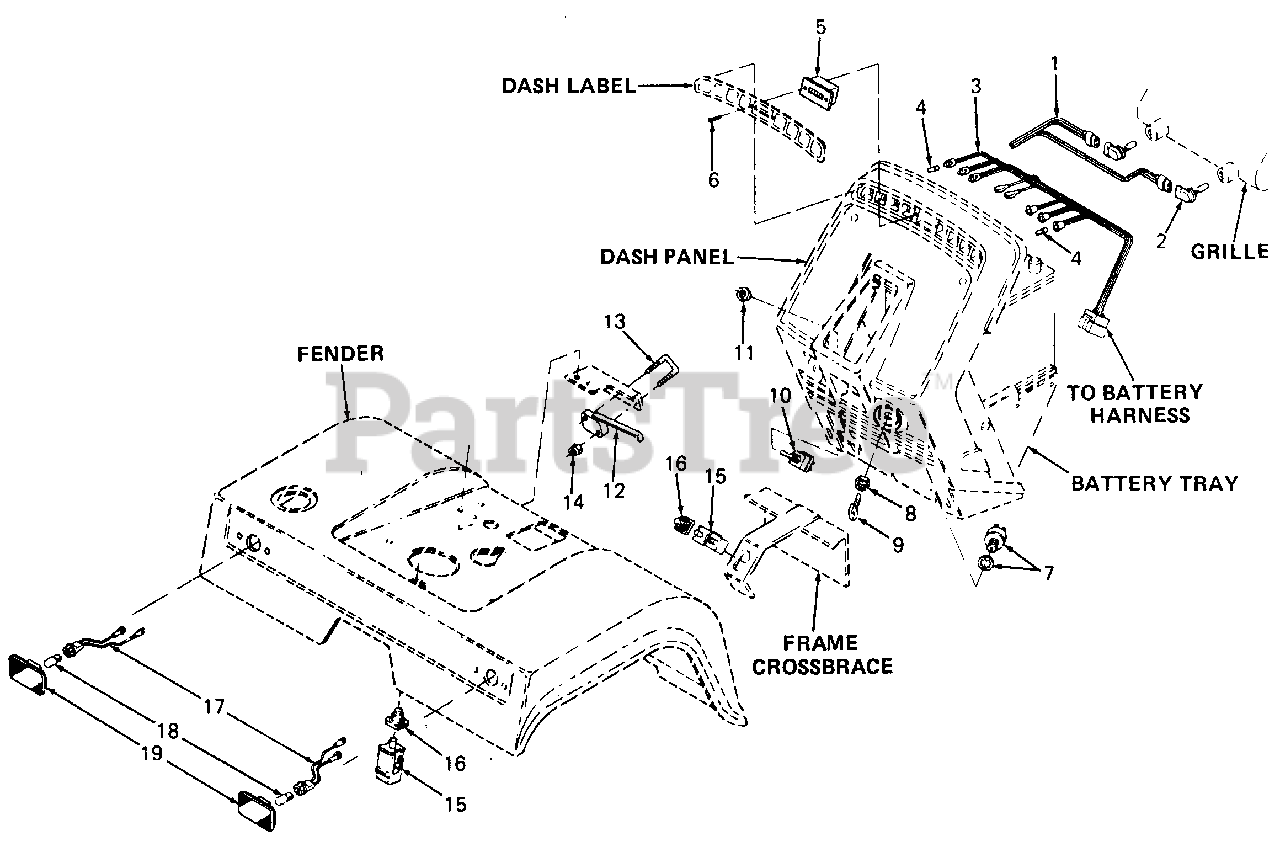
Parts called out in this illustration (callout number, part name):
1	Harness, Main Wire
2	Bulb, Head Lamp
3	Harness, Indicator Wire
4	Bulb, Indicator
5	Hour Meter
6	Screw, Truss Hd Tapp, #6 X .
7	Switch, Ignition
8	Nut, Ignition Switch
9	Key, Ignition (Set of 2)
10	Switch, PTO
11	Nut, Hex, 1/2-27 X .100 Thk
12	Switch, Reverse
13	Screw, Switch
14	Nut, Hex Insert Lock, #4-40
15	Switch, Interlock
16	Boot, Switch
17	Cable Assy, Tail Light
18	Bulb, Tail Light
19	Lens Assy, Tail Light
